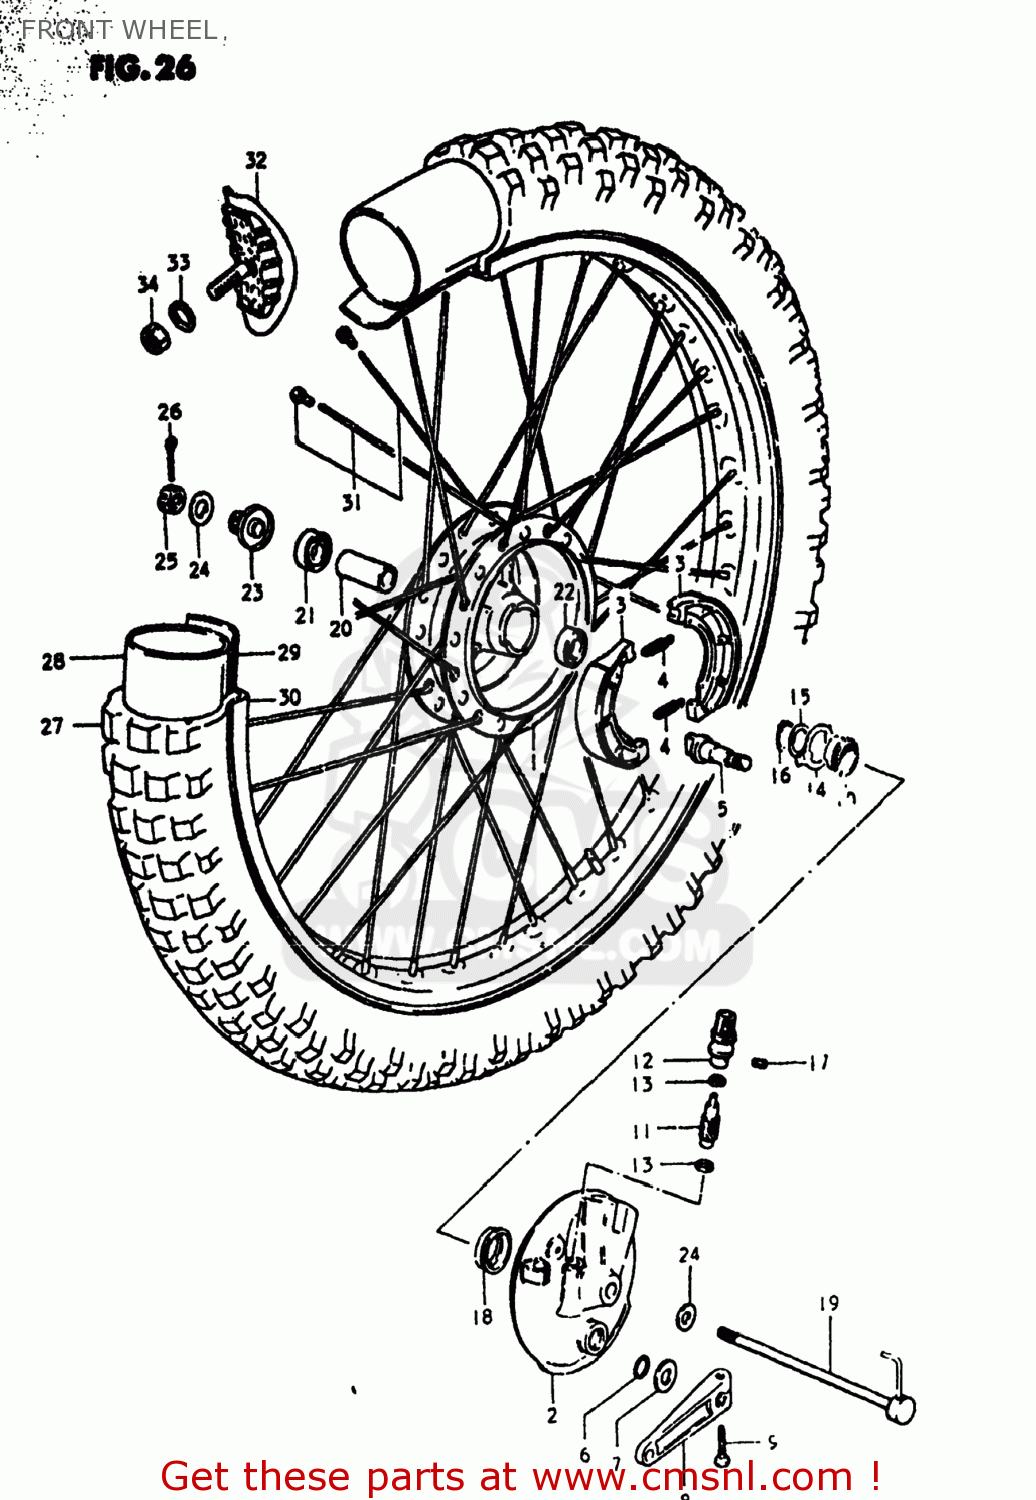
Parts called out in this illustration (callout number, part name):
1	HUB,FRONT
2	PANEL,FRONT HUB
3	SHOE BRAKE (MCA)
4	SPRING(L:34)
5	CAM,FRONT BRAKE
6	O RING(D:2.5,ID:11.4)
7	WASHER(12.5X20X1)
8	LEVER,FRONT BRAKE CAM
9	BOLT
10	GEAR,SPEEDOMETER
11	PINION,SPEEDOMETER
12	BUSH,METER GEAR OUTER
13	WASHER (5.1X9X0.4)
14	DRIVER,SPEEDOMETER GEAR
15	WASHER(18.5X24X1)
16	CIRCLIP
17	SCREW
18	OIL SEAL (43X58X7)
19	AXLE,FRONT
20	SPACER (12.6X19X52)
21	BEARING, RH
22	BEARING
23	SPACER,FRONT AXLE,RIGHT
24	WASHER
25	NUT, REAR AXLE
26	COTTER PIN
27	TIRE,FRONT
28	TUBE,INNER
29	PROTECTOR,WHEEL,INNER
30	RIM,FRONT WHEEL
31	SPOKE SET,FRONT
32	STOPPER,BEAD
33	WASHER
34	NUT
